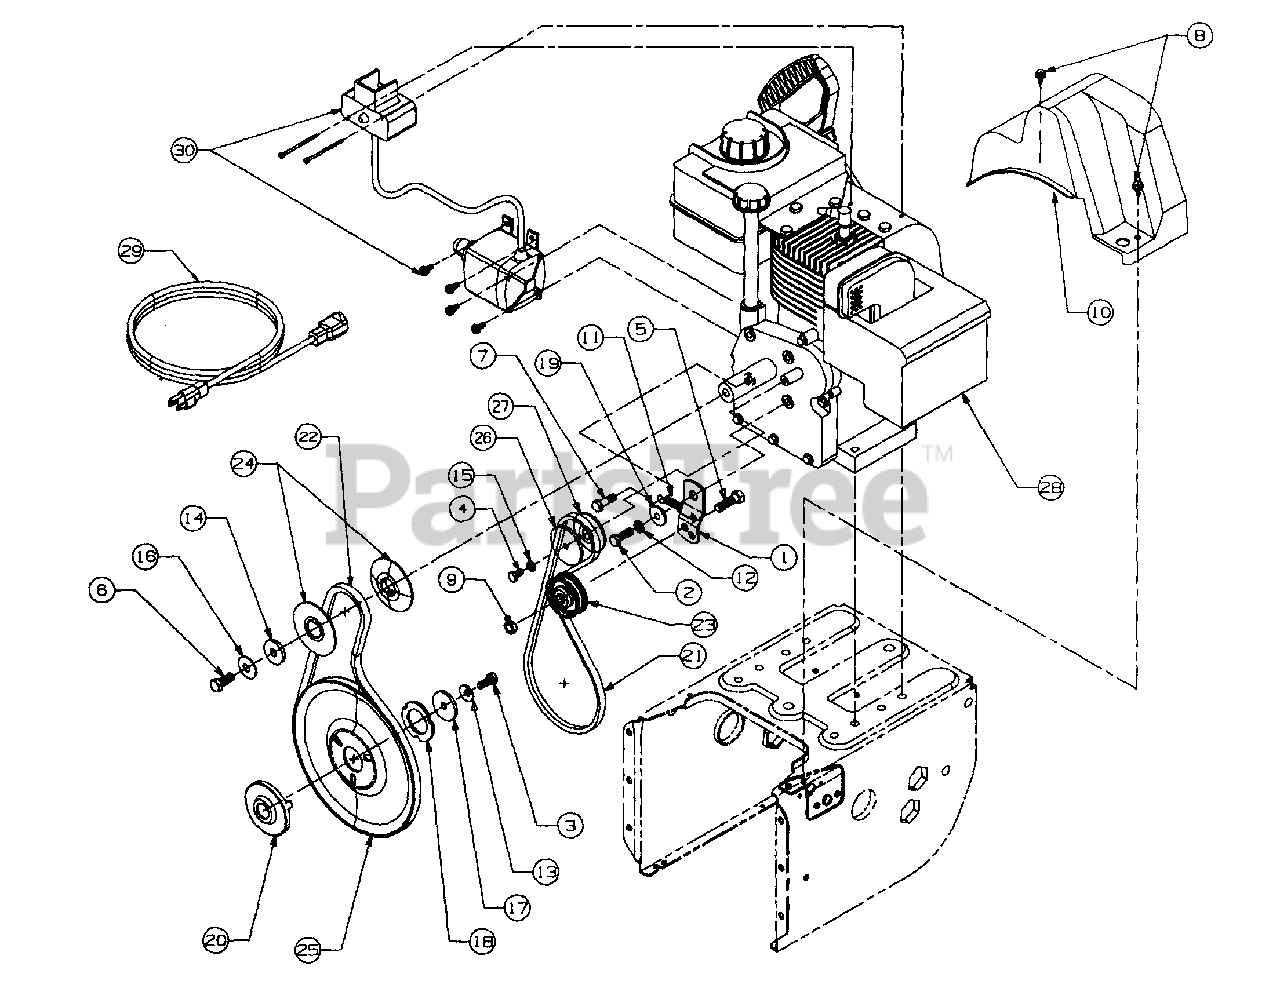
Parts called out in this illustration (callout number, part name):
5	Screw
9	Nut, Hex Jam
10	Belt Cover
11	Spring
13	Washer - Bell
15	Washer
16	Washer - Bell
17	Washer - Flat
18	Washer
20	Pulley, Adapter
21	V-Belt
22	V-Belt Matched
23	Idler, Flat
24	Pulley, Half
25	Pulley, Auger
26	Pulley Half
27	Pulley, Half
28	Engine
29	Cord Extension
30	Starter
